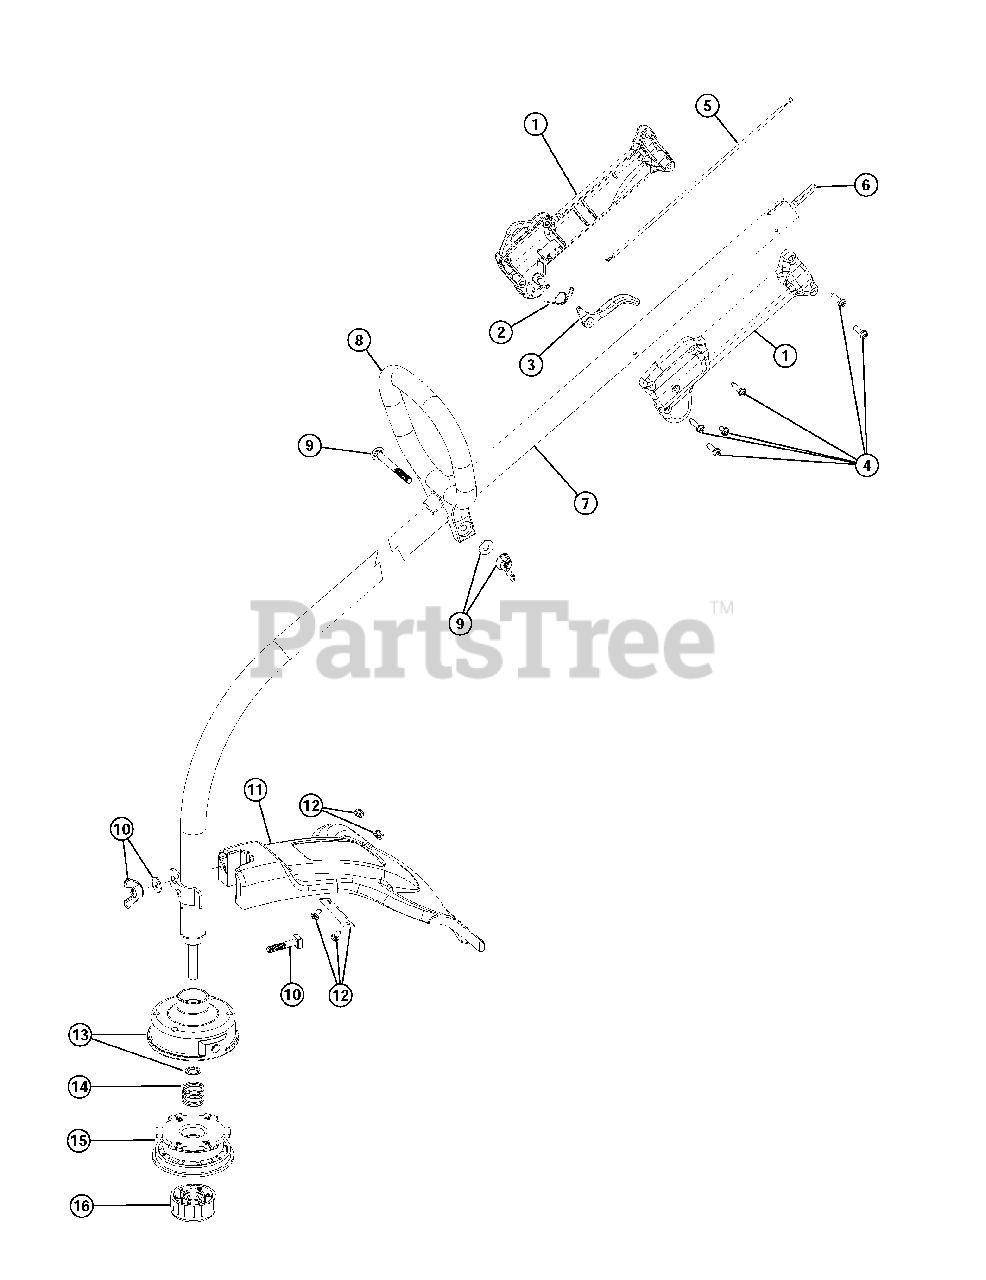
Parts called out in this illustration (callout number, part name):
1	Throttle Housing and Trigger Assembly
2	Throttle Trigger Spring
3	Throttle Trigger
4	Throttle Housing Screws
5	Throttle Cable
6	Flexible Drive Shaft
7	Drive Shaft Housing Assembly
8	D-Handle Assembly
9	D-Handle Hardware
10	Guard Mounting Hardware
12	Blade Assembly
13	Outer Reel w/Retainer
14	Spring
15	Inner Reel
16	Bump Knob
